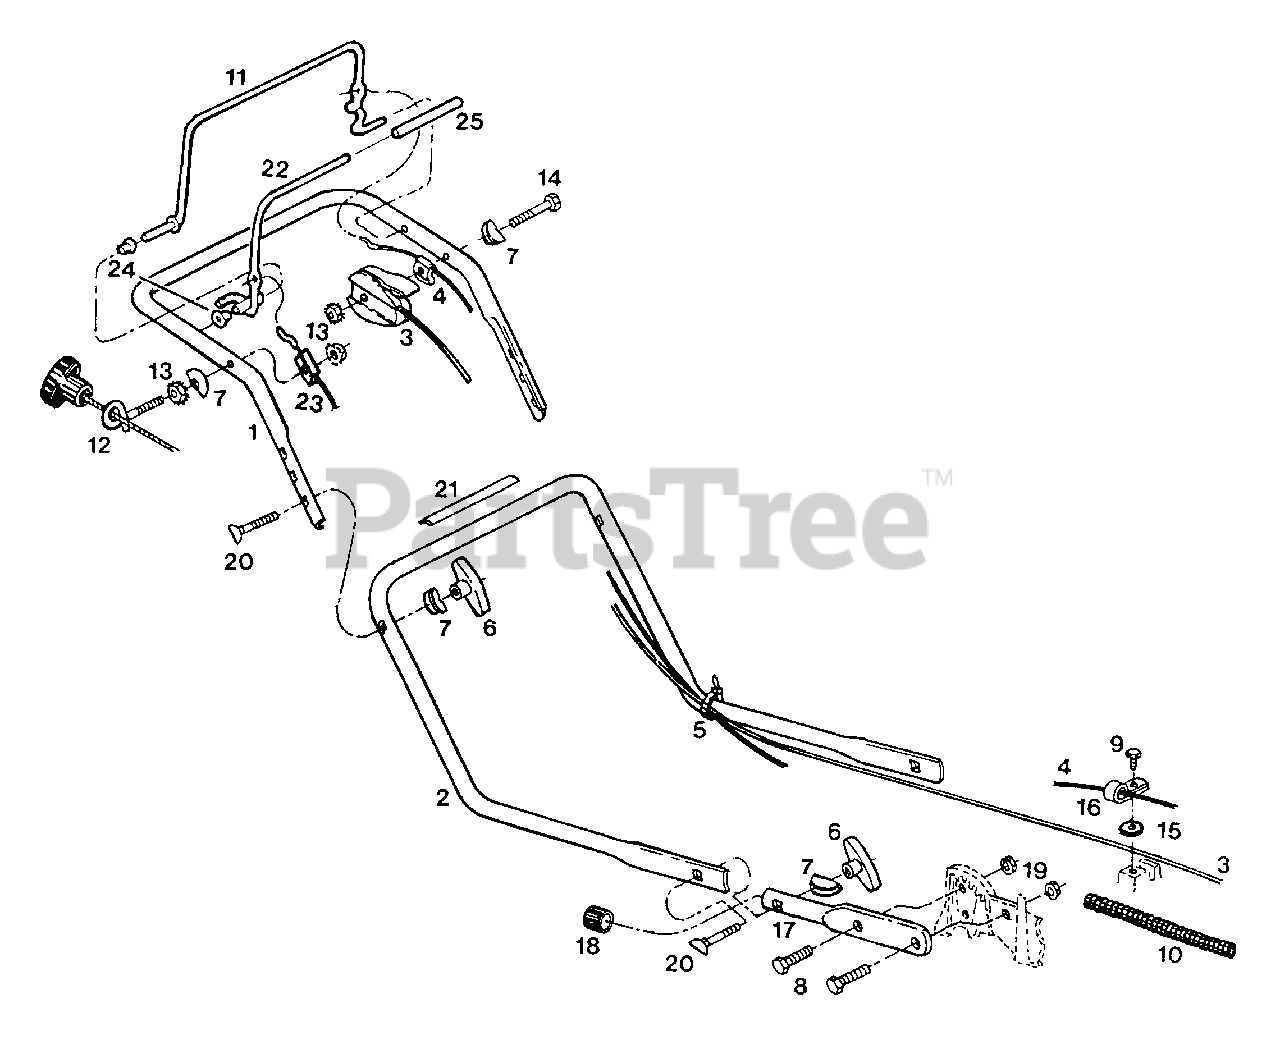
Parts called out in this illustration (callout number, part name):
1	Handle - Upper
2	Handle - lower
3	Control - throttle w/cable
4	Cable - engine/blade control
5	Cable Tie
6	Wing Nut - plastic
7	Washer - 5/16 curved
8	Bolt - hex 5/16-18 x 1
9	Screw - 1/4-20 x 5/8 hex tap
10	Cover - cable
11	Bail - engine/blade control
12	Eyebolt - rope guide
13	Nut - hex 1/4-20 keps
14	Bolt - hex 1/4-20 x 2 1/2
16	Clamp - engine control cable
17	Stub - handle mounting
18	Plug - stub end
19	Nut - hex 5/16-18 flnge lock
20	Bolt - handle, curved head
21	Decal - Starting Instructions
22	Bail - ground drive control
23	Cable - drive control
24	Bushing - control bail
25	Sleeve - control bail
